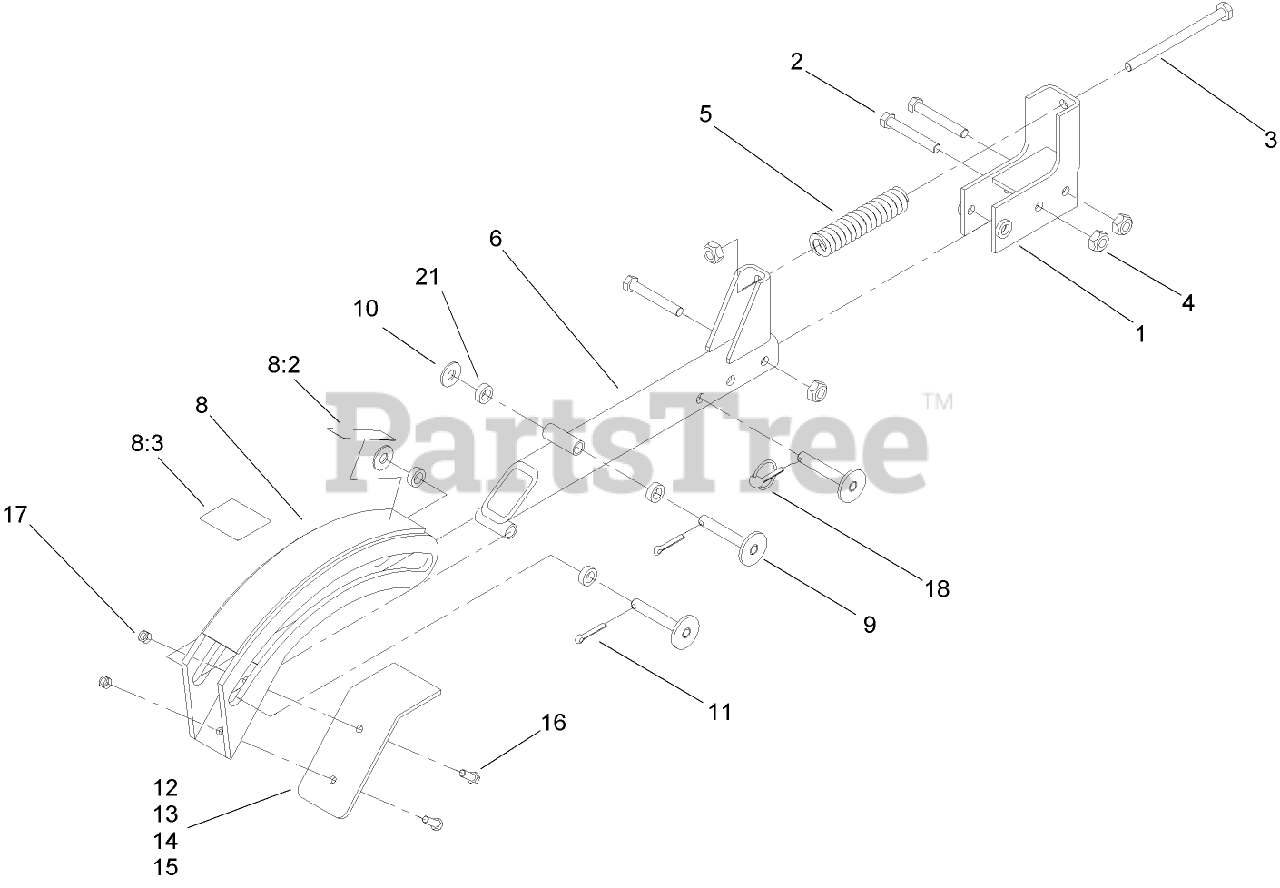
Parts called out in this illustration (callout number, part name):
1	BRACKET SPRING ASM
2	SCREW-HH
3	SCREW-HH
4	NUT-HEX
5	Spring-Comp
6	CRUMBER SUPPORT ASM
8	CRUMBER SLIDE ASM
8:2	DECAL-WARNING
8:3	DECAL-WARNING
10	WASHER-FLAT
11	PIN-COTTER
12	PLATE-4 inch
13	PLATE-6 inch
14	PLATE-8 inch
15	PLATE-12 inch
16	SCREW-HH
17	NUT-HEX
18	PIN-LYNCH
21	BUSHING
